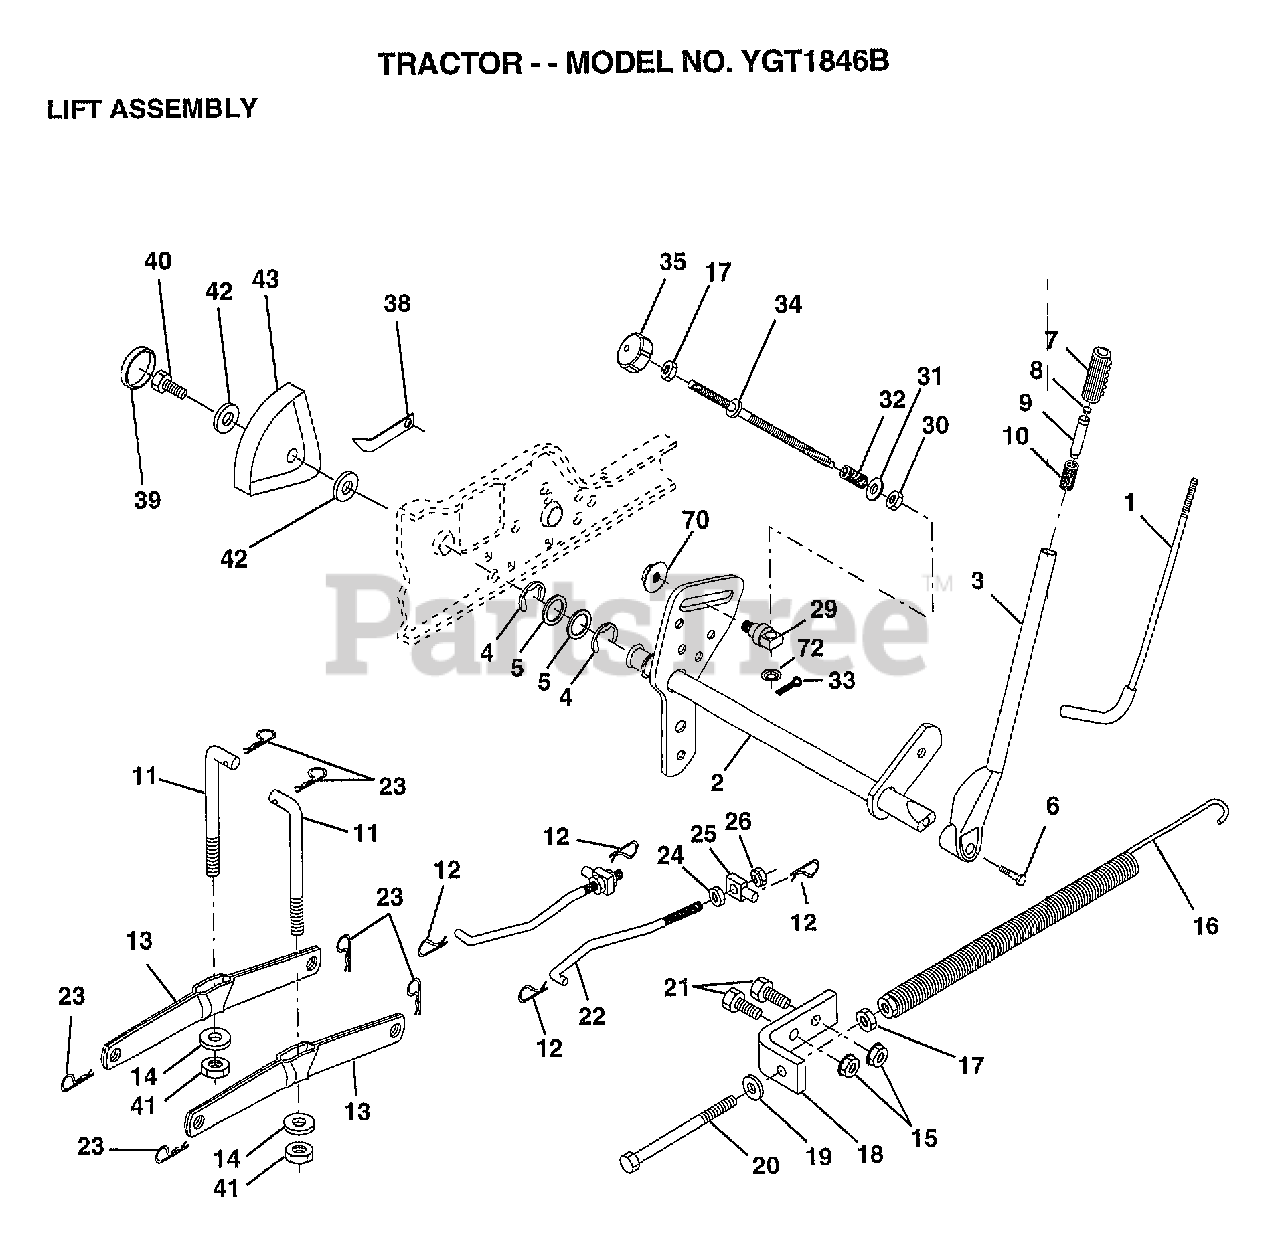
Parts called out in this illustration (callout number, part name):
1	LEVER ROD LT
2	SHAFT.ASM.LIFT.VGT
3	LEVER.ASM.LIFT.RH
4	E-RING
5	WASHER
6	"BOLT,HEX"
7	GRIP HANDLE
10	SPRING T
11	LINK.LIFT.MWR.VGT
12	RETAINER SPRING
13	ARM SUSP REAR
14	BEARING PVT LH
17	NUT
18	BRACKET SPRING AS
19	WASHER
20	BOLT-ADJ SPRING T
21	BOLT
22	LINK.FRONT
24	NUT
25	TRUNION
26	NUT.LK.W/WSH.1/2.
29	TRUNNION
30	NUT T
31	WASHER
32	SPRING.COMP.INF.H
34	ROD.ADJ.LIFT
35	KNOB INF 3/8-16
38	POINTER-INDICAT
39	"PLUG,HOLE"
40	SCREW
41	NUT.CROWNLOCK.3/8
42	WASHER
43	HEIGHT INDICATOR
70	NUT.HXFLG.LOCK.
72	NUT PUSH M
